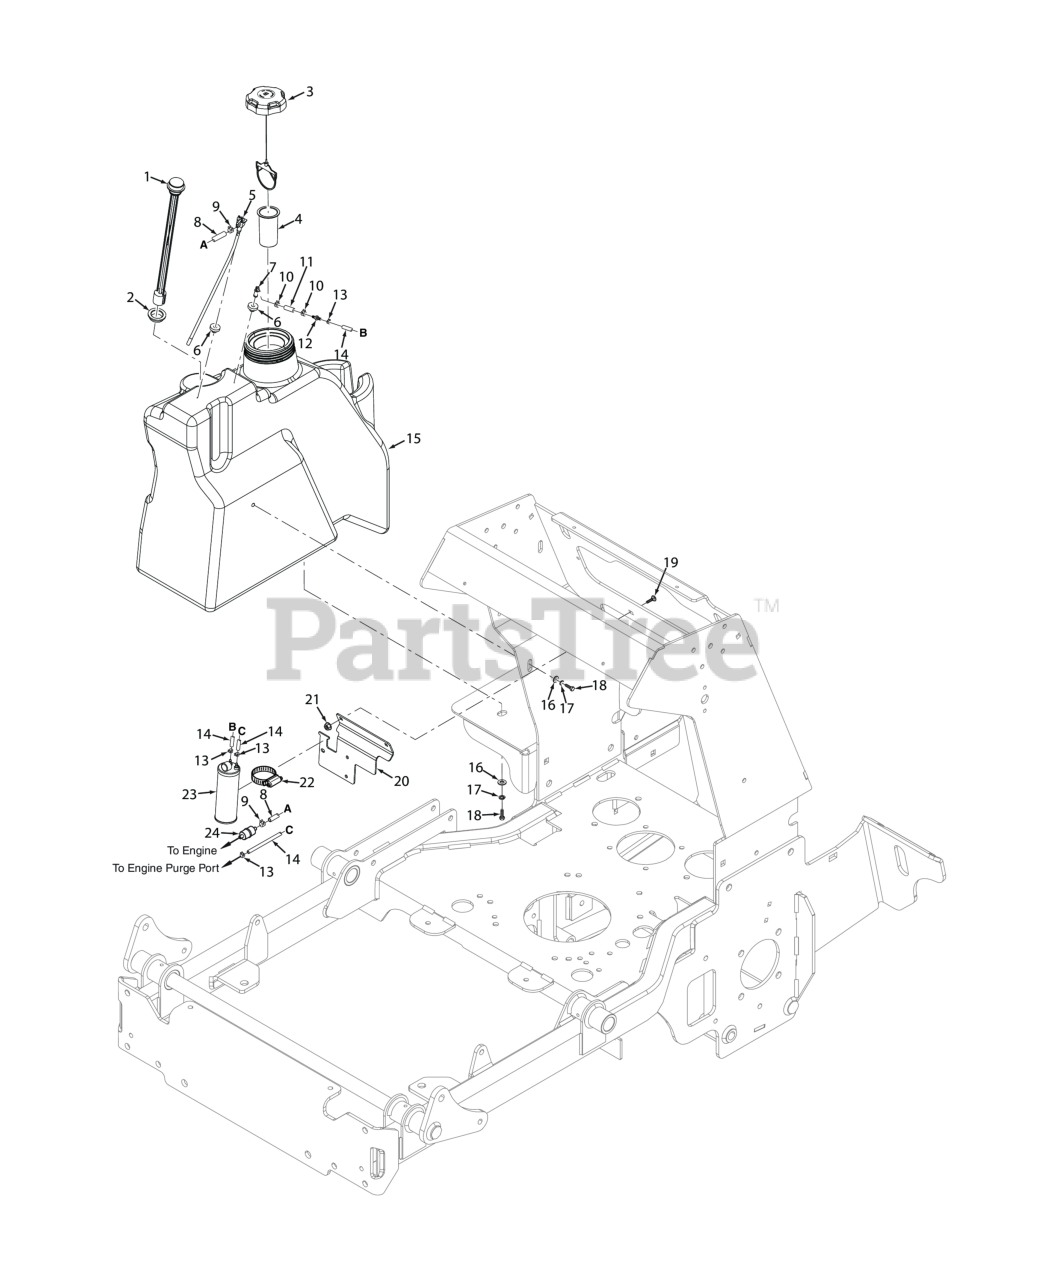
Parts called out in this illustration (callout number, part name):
1	Fuel Gauge Assy., 14.6" (32)
2	Grommet, Fuel Gauge
3	Fuel Cap w/ Tether (E.P.A.)
4	Tube, Fuel Tank Insert - 4"
5	Valve, Fuel Shutoff (32)
6	Bushing, 0.56" Dia. Viton
7	Remote Vent
8	Fuel Hose, 1/4" I.D. Non-Perm (791DFI Fuel Return) - Order by Inch
9	Clamp, Fuel Hose 1/4" Hose I.D.
10	CLAMP, FUEL HOSE(KAWASAKI ONLY)
11	Hose, 1/4" Vapor Recovery (order by inch)
12	Mender, 1/4 x 3/16 w/0.02 Hole
13	Clamp, Vapor Recovery Hose 3/16"
14	Hose, Vapor Recovery 3/16" (order by inch)
15	Fuel Tank Assy., SVRII-32
16	Flatwasher, 5/16-.375 x .875 x .083 (35BV & 37BV-EFI)
17	Lockwasher, 5/16 (.317 x .586 x .078) Helical Spring
18	BOLT, SERRATED FLANGE HEX HEAD 5/16-18 X 3/4"
19	Bolt, 5/16-18 x .75 RHSN Carriage
20	Bracket, Hydro Tank Mounting
21	Nut, Serrated Flange 5/16-18 (Right Front Engine Mounting, Briggs and Kohler Only)
22	Clamp, 3-1/2" Max. Dia.
23	Carbon Canister - SVR-52V / SVR-61V
24	Fuel Filter
